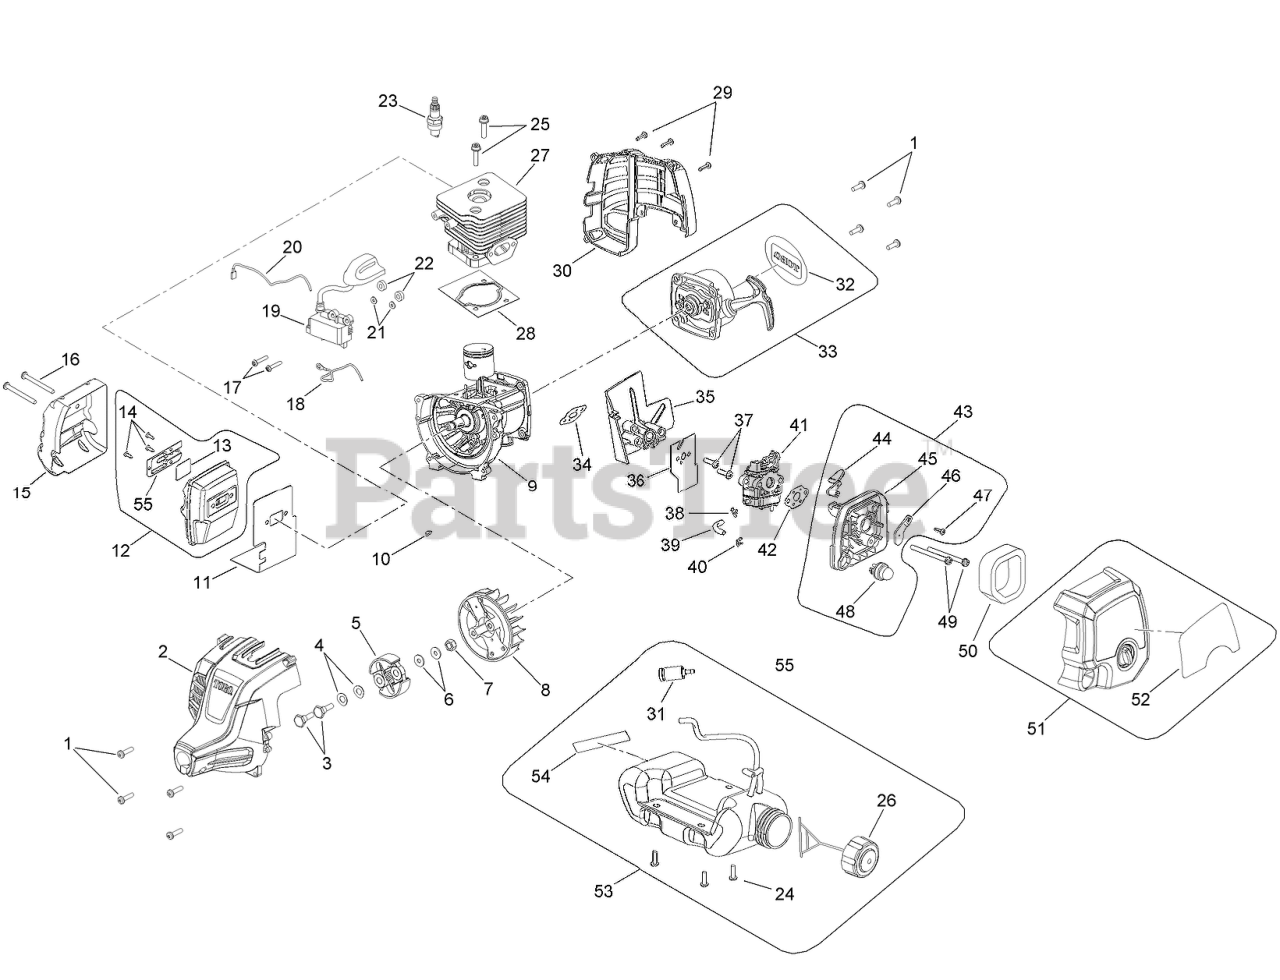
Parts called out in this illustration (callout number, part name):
1	SCREW-PH
2	HOUSING-ENGINE, FRONT
3	SCREW-CLUTCH
4	WASHER-CURVED
5	CLUTCH ASM
7	NUT-ROTOR
9	CRANKCASE ASM
10	KEY-WOODRUFF
11	GASKET-MUFFLER
12	MUFFLER ASM
14	SCREW-PH
15	SHIELD-HEAT
16	SCREW-PH
17	SCREW AND WASHER
18	WIRE-LEAD, RED
19	COIL BOOT ASM
20	WIRE-LEAD, BLACK
23	SPARK PLUG
24	T25 TORX PAN HEAD
25	SCREW-SOCKET HEAD
26	CAP-FUEL
27	CYLINDER
30	HOUSING-ENGINE, REAR
31	FILTER-FUEL
32	PLATE-LOGO
33	RECOIL STARTER AND STARTER CUP ASM
34	GASKET-HEAT DAM
35	HEAT DAM
38	CLIP-HOSE
39	FUEL LINE 45MM
40	CLIP-HOSE
41	CARBURETOR ASM
42	GASKET-CARBURETOR
43	FILTER HOUSING ASM
44	LEVER-CHOKE
45	PLATE-CARBURETOR
46	PLATE-CHOKE
47	SCREW-PH
48	PRIMER ASM
49	T20 TORX CAP SOC HD
50	ELEMENT-FILTER, AIR
51	COVER ASM
52	DECAL-START
53	FUEL TANK AND CAP ASM
54	COMBUSTION WARNING LABEL
55	COVER-TRIMMER
